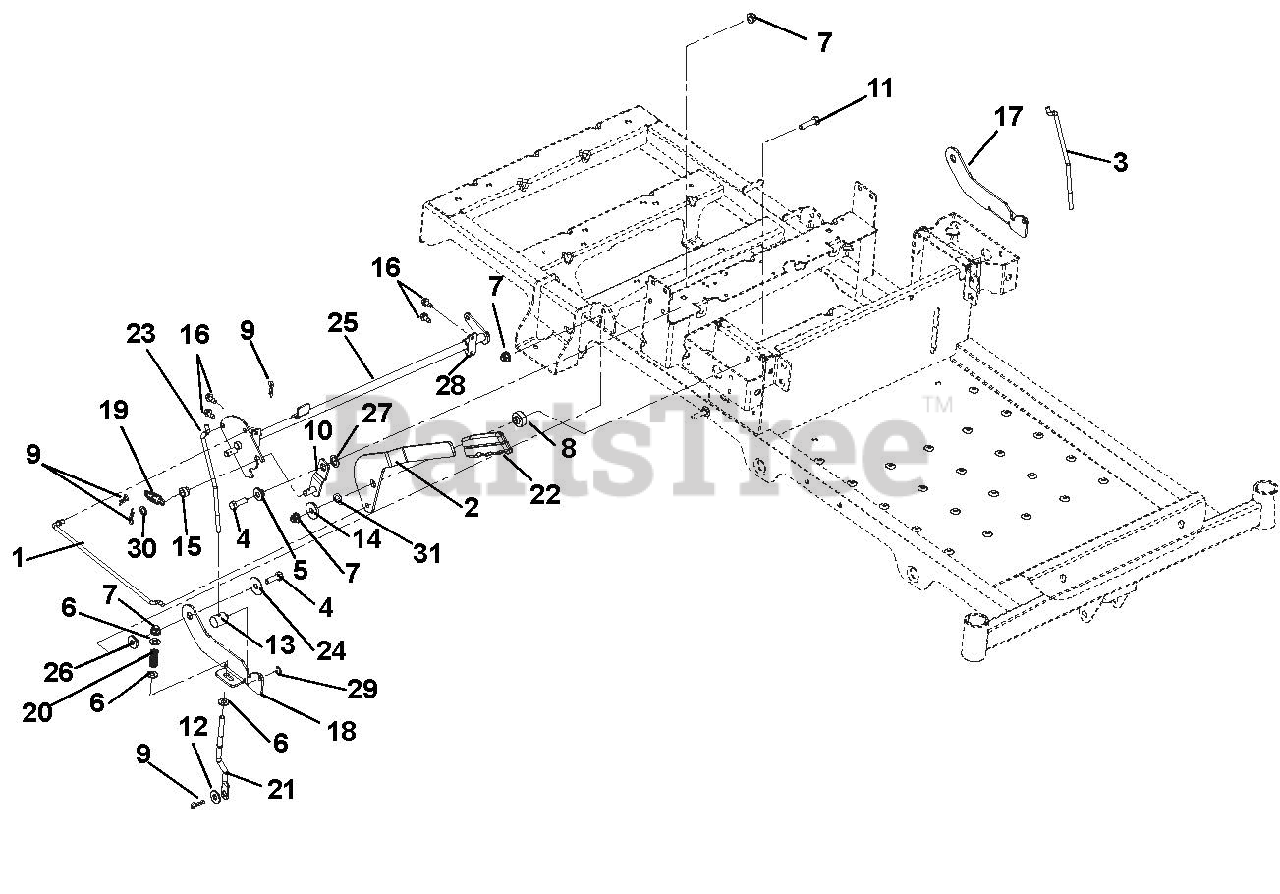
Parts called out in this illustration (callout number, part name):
1	LINK, BRAKE HANDLE
2	HANDLE, PARKING BRAKE
3	LINK, NEUTRAL LH
4	BLT,HEX .31-18X1.00 G5 ZCC
5	BSHG-FLG .32X.500X.344X.880
6	WSHR,FLT .344X.688X.065 ZCC
7	NUT,LK-NYL-FLG .31-18 G5ZC120
8	SPCR,BRAKE .32X.49X.192X1.00
9	PIN, HAIR #213 .08X1.19 ZCC
10	WELDMENT,DETENT ARM
11	BLT, HEX .31-18X1.25 G5 ZCC
12	WSHR,FLT .375X.875X.083 ZCC
13	TRUNION, 1/4-20
14	WSHR, FLT .340X1.125X.135 ZCC
16	SCR-TAP .25-20X.50 HWH ZCC
17	LATCH, LH NEUTRAL
18	LATCH, RH NEUTRAL
19	SG-TENS .072X.565X1.87
20	SPRING, COMPRESSION
21	LINK, BRAKE COG
22	GRIP, PARKING BRAKE (YELLOW)
23	LINK, NEUTRAL RH
24	WSHR, FLT .347X1.254X.048 ZCC
25	WLDMT, BRAKE SHAFT
26	BSHG, FLG .325X.499X.26X.88
27	WSHR, FLT .520X.827X.062 ZCC
28	BUSHING-.50 CLAMP BLOCK MOLDED
29	RG-RTNG-EXT .250X.025
30	WSHR, FLT .385X.745X.030 ZCC
31	WSHR-WAVE .50X.75X.015 .13FRHT
